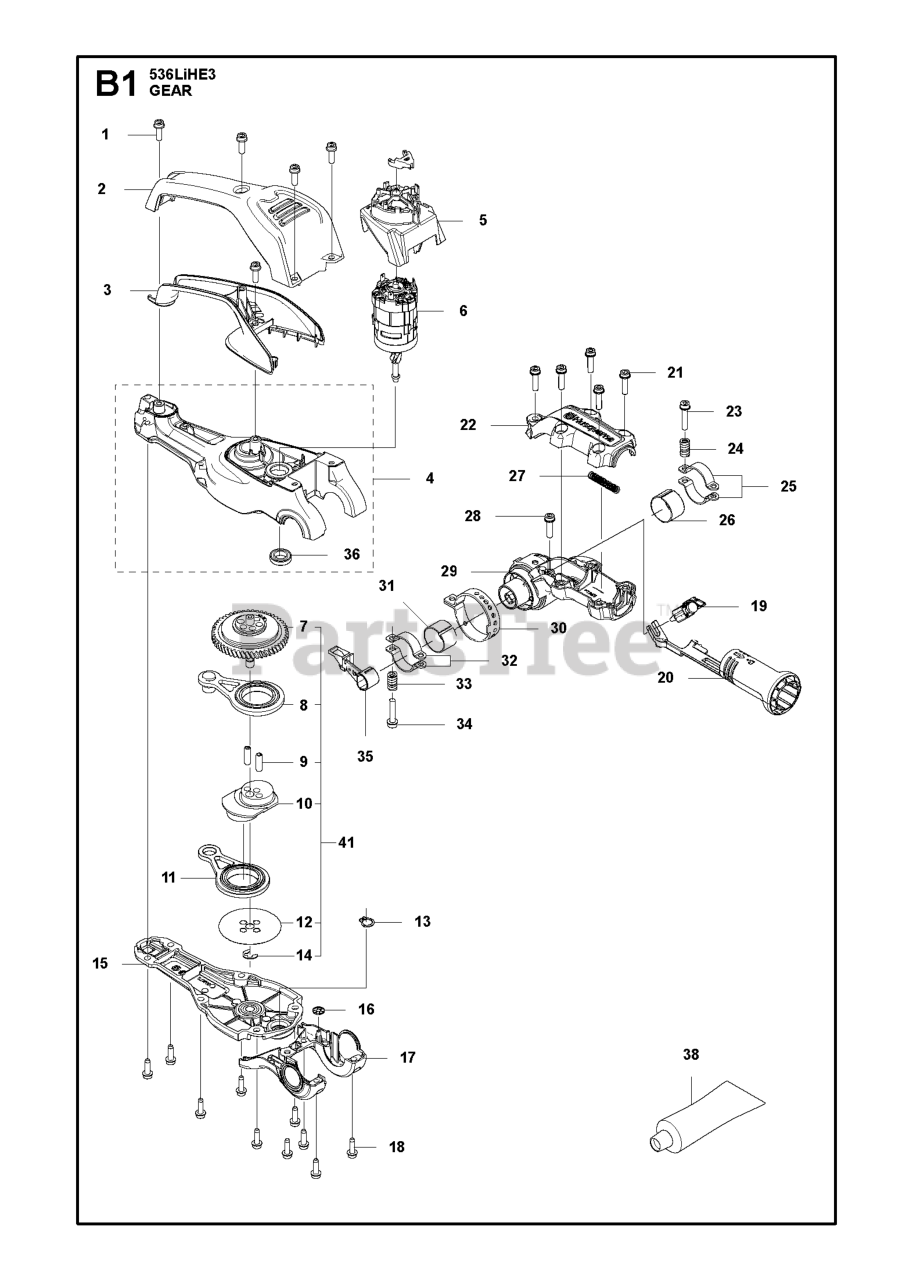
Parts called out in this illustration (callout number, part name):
1	SCREW IHSCFT
2	MOTOR COVER UPPER
3	MOTOR COVER LOWER
4	GEAR HOUSING ASSY
5	AIR CONDUCTOR MOTOR
6	MOTOR ASSY
9	HEAVY DUTY DOWEL PIN PROJEKT 1
10	ECCENTRIC DISC GEAR
12	WASHER DISK DISC
13	SEEGER CLIP
14	LOCK WASHER
15	COVER ASSY GEAR HOUSING ASSY S
16	LOCK WASHER
17	BEARING CAP
18	SCREW IHSCFT
19	LOCKING PIN ASSY
20	HANDLE GRIP
21	SCREW IHSCFT
25	BRAKE BAND ASSY POLE HEDGETRIM
26	SLIDE RING
27	COMPRESSION SPRING
28	SCREW IHSCFT
29	HOUSING JOINT
30	RING INDEX 520IHE3/IHT4
31	SLIDE RING
32	BRAKE BAND ASSY POLE HEDGETRIM
36	BALL BEARING
41	GEAR ASSY GEAR ASSY KIT 520IHE
